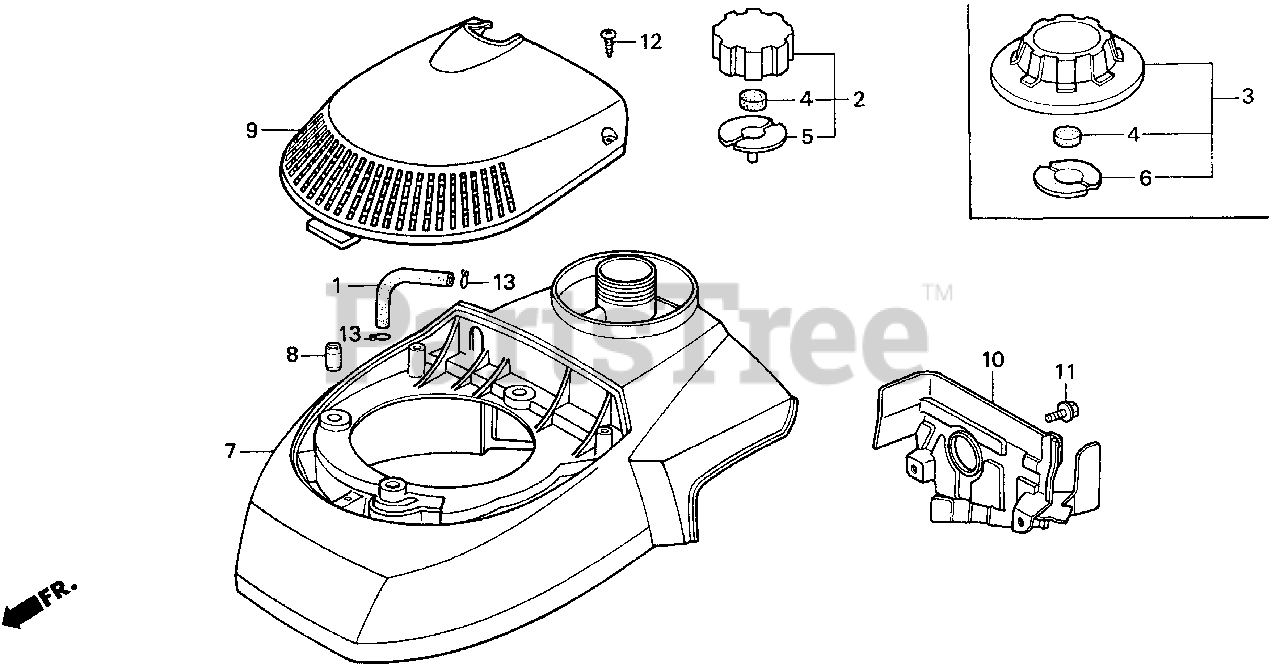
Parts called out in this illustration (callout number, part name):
1	TUBE, FUEL
3	CAP ASSY., FUEL TANK
4	SPONGE, FUEL CAP BREATHER
6	GASKET, FUEL CAP
7	COVER, FAN *R8* (BRIGHT RED)
8	COLLAR, RECOIL STARTER
9	HOOD, FAN COVER *R8* (BRIGHT RED)
10	COVER, TOP
11	BOLT, FLANGE (6X12) (CT200)
12	SCREW, TAPPING (4X20)
13	CLIP, TUBE (B8)
